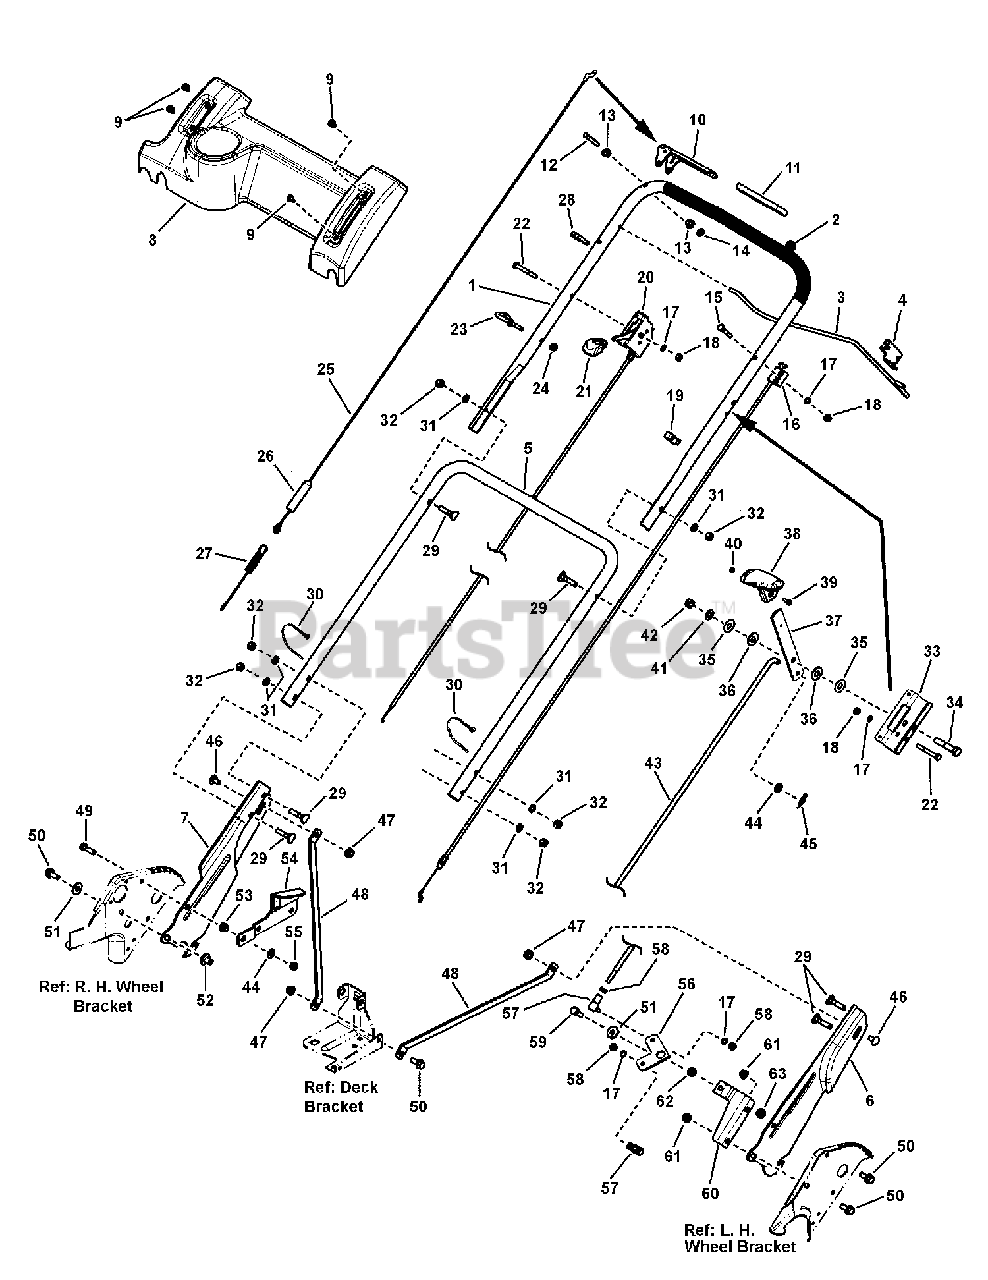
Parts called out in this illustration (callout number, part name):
1	HANDLE, Upper
2	FOAM GRIP, 18.75" long
3	BAIL, OPC Control
4	CLIP, Zone Control
5	HANDLE, Middle
6	HANDLE, Lower, Adjustable, LH
7	HANDLE, Lower, Adjustable, RH
8	CONTROL PANEL, No Electric Switch
9	SCREW, 1/4-20 x .550" Pan Head Self-Tap (Torx)
10	HANDLE, Clutch
11	GRIP, International Symbol
12	PIN, 1/4 x 1-1/2"
13	BUSHING, .27 x .35 x .4 Flange
14	PUSH-NUT, 1/4"
15	SCREW, 1/4-20 x 1-1/2" Hex Head Cap GR 5
16	CABLE, Zone Control, W14
17	WASHER, 1/4" Internal Tooth Lock, YZ
18	NUT, 1/4-20 Hex, GR 5
19	CLIP, Wiring Harness
21	KNOB, Throttle
22	SCREW, 1/4-20 x 2" Hex Head Cap, GR 5
23	GUIDE, Rope (1/4-20 thread)
24	NUT, 1/4-28 Hex GR 5 or B
25	CONTROL, Clutch, 21"
26	COVER, Vinyl
27	SPRING, Clutch
28	CLAMP, 7/8" Double Cable
29	BOLT, 5/16-18 X1-1/2" Curved Head Square Neck, GR 2 BZ
30	CABLE-TIE, 7"
31	WASHER, 5/16" Internal Tooth Lock
32	NUT, 5/16-18 Hex, GR 5 or B, BZ
33	BRACKET, Shift
34	SCREW, 3/8-16 x 2" Hex Head Cap, GR 5
35	WASHER, 7/16" Flat
36	WASHER, Nylon
37	LEVER, Shift
38	KNOB, Shift
39	SCREW, #8-32 x 1/2" Cross Recess Filister Head Machine
40	NUT, #8-32 Hex
41	WASHER, Belleville
42	NUT, 3/8-16 Hex Center Lock
43	ROD, Speed Control
44	WASHER, .34 x .69 x .08 Flat, YZ
45	COTTER PIN, 5/16" Self Lock
46	BOLT, 5/16-18 x 5/8" Round Head Short Square Neck, GR 5 BZ
47	NUT, 5/16-18 Hex Flange Lock, GR 5, YZ
48	BRACE, Handle
49	SCREW, 5/16-24 x 1" Hex Head Cap, GR 5, BZ
50	BOLT, 5/16-18 x 3/4" Hex Flange Lock
51	WASHER, .327 x .875 x .09 Flat, BZ
52	T-NUT, 5/16-18
53	BUSHING, Differential
54	LINK, Differential, Commercial
55	NUT, 5/16-24 Hex Center Lock, GR B, BZ
56	BELL CRANK, Black Zinc
57	BALL JOINT
58	NUT, 1/4-28 Hex GR 5 or B, YZ
59	SCREW, 5/16-18 x 7/8" Hex Head Cap, GR 5 YZ
60	BRACKET, Bell Crank
61	NUT, 5/16-18 Hex Flange Lock, GR 5
62	SPACER, .623 OD x .328 ID x .151 L
63	NUT, 5/16-18 Hex Center Lock
